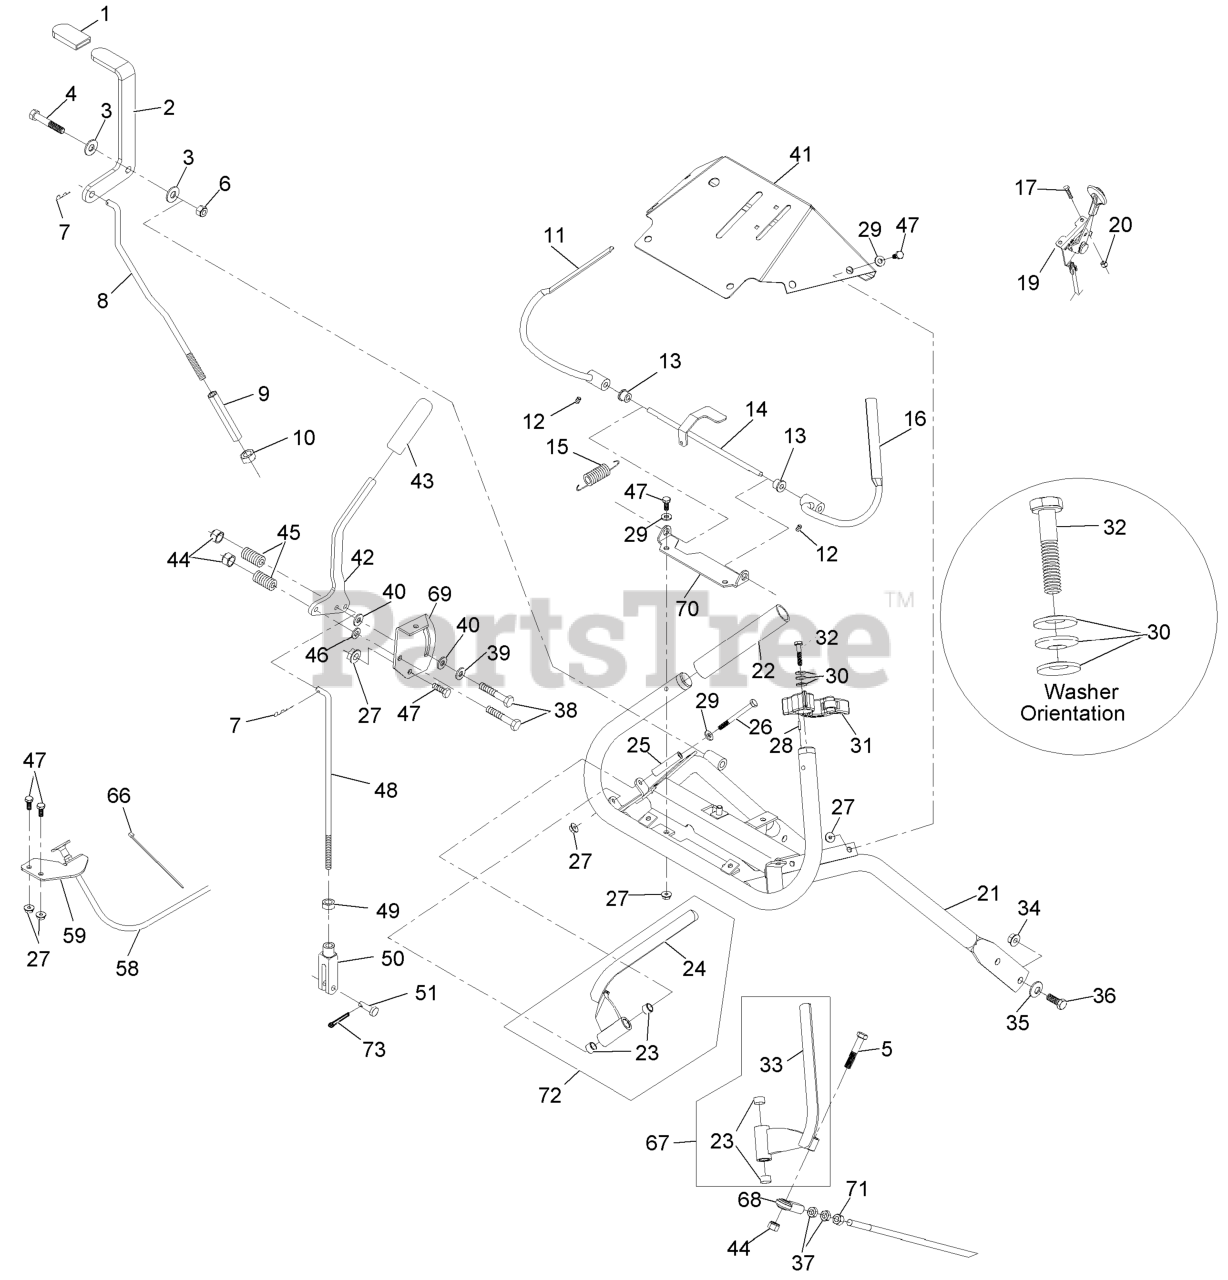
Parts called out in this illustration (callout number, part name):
1	GRIP-LEVER
2	ASM, LEVER W/GRIP
3	WASHER-FLAT
4	SCREW-HH
5	SCREW-HH
6	NUT-LOCK, NI
7	PIN-COTTER
8	LINK,BLADE ENGAGE (PLTD)
9	TURNBUCKLE
10	NUT-HEX
11	WLD,LH OPC LEVER
12	SCREW-SET
13	BUSHING-NYLON
14	WLD,OPC LEVER AXLE
15	SPRING-EXTENSION
16	WLD,RH OPC LEVER
17	BOLT-CARR
19	CONTROL, THROTTLE
20	NUT-LOCK, NI
21	WLD,UPPER ECS HANDLE
22	GRIP-BAR, HANDLE
23	BUSHING-SLEEVE
24	Lever, Drive Lh
25	BUSHING-LEVER, DRIVE
26	SCREW-HH
29	WASHER-FLAT
30	WASHER-SPRING
31	ASM,LATCH RH THUMB
31	ASM,LATCH LH THUMB
32	SCREW-HH
33	Lever, Drive Rh
34	NUT-HHF, WHIZ
35	WASHER-BELLEVILLE
36	SCREW-HH
37	NUT-HJ
38	SCREW-HH
39	WASHER-FRICTION
40	WASHER-FRICTION
41	ASM,CONSOLE W/DECALS
42	LEVER, SHIFT W/GRIP
43	GRIP-HANDLE, STEERING
44	NUT-LOCK, NI
45	SPRING-COMPRESSION
46	WASHER-PLAIN
47	SCREW-HH
48	ROD,SPEED CONTROL
49	NUT-JAM
50	YOKE-ADJUSTABLE
51	PIN-CLEVIS
58	CABLE-CHOKE
59	BRACKET-CABLE, CHOKE
66	TIE-CABLE
67	DRIVE LEVER-ASM, RH
68	JOINT-BALL, END
69	BRACKET,SHIFTER SLIDE (PL
70	BRACKET,OPC AXLE
71	NUT-HEX
72	DRIVE LEVER-ASM, LH
73	PIN-COTTER
